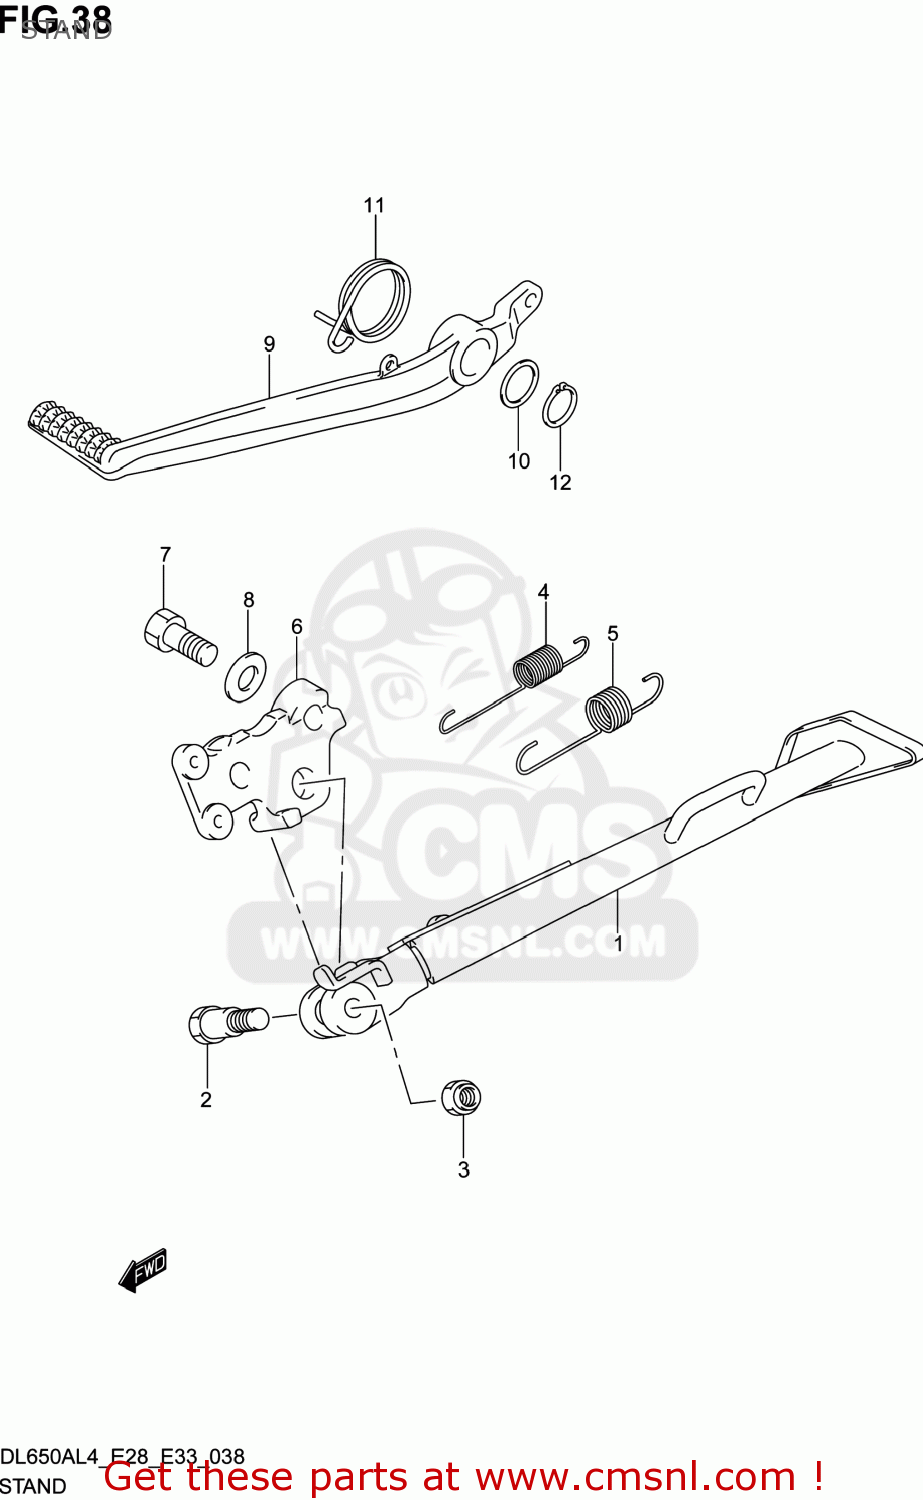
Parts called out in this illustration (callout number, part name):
1	STAND,PROP
2	BOLT(10X37.5)
3	NUT,PROP STAND
4	SPRING
5	SPRING
6	BRACKET,PROP STAND
7	BOLT(12X30)
8	WASHER(12.5X24X2.6)
9	PEDAL,BRAKE
10	WASHER(18X24X1)
11	SPRING
12	CIRCLIP
